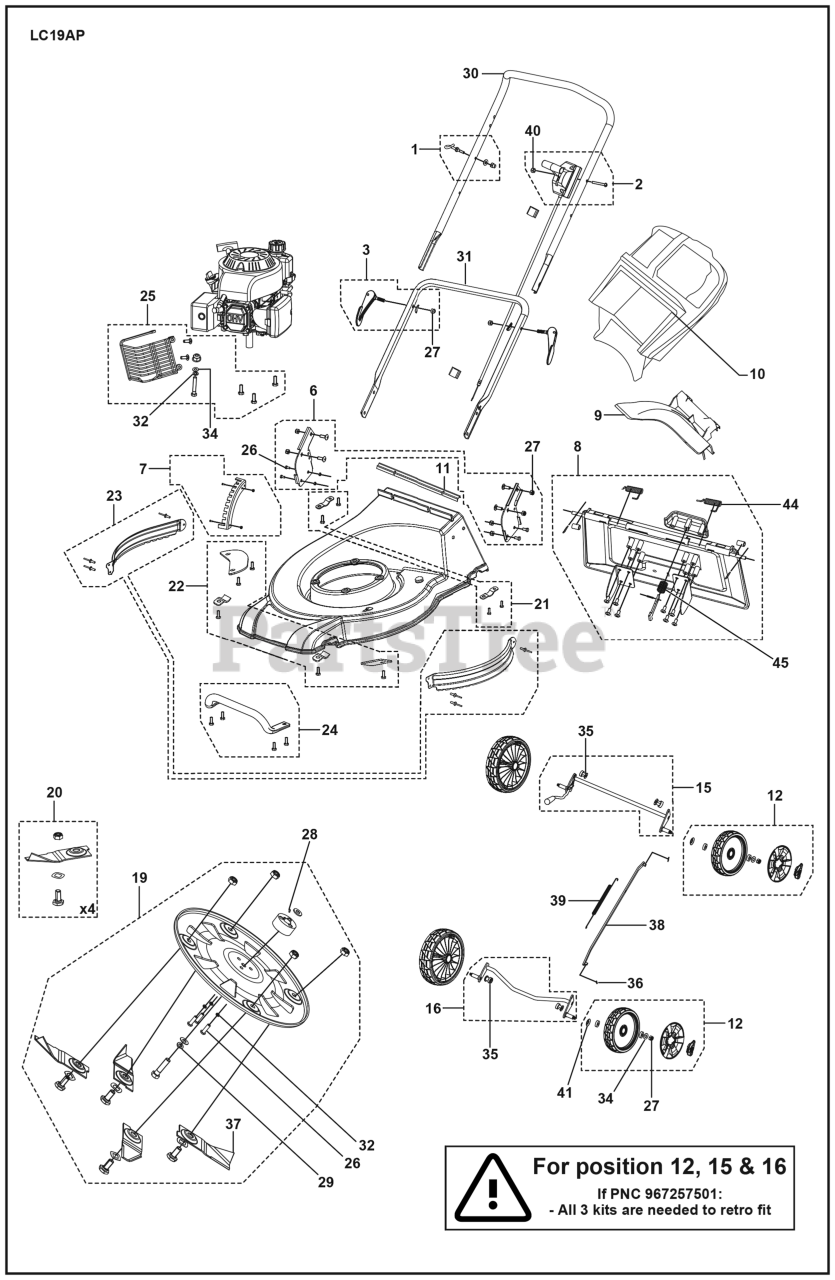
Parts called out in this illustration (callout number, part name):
27	LOCKNUT M8
29	Spring Washer
32	WASHER SPRING LOCK WASHER WITH
40	LOCKNUT M6
